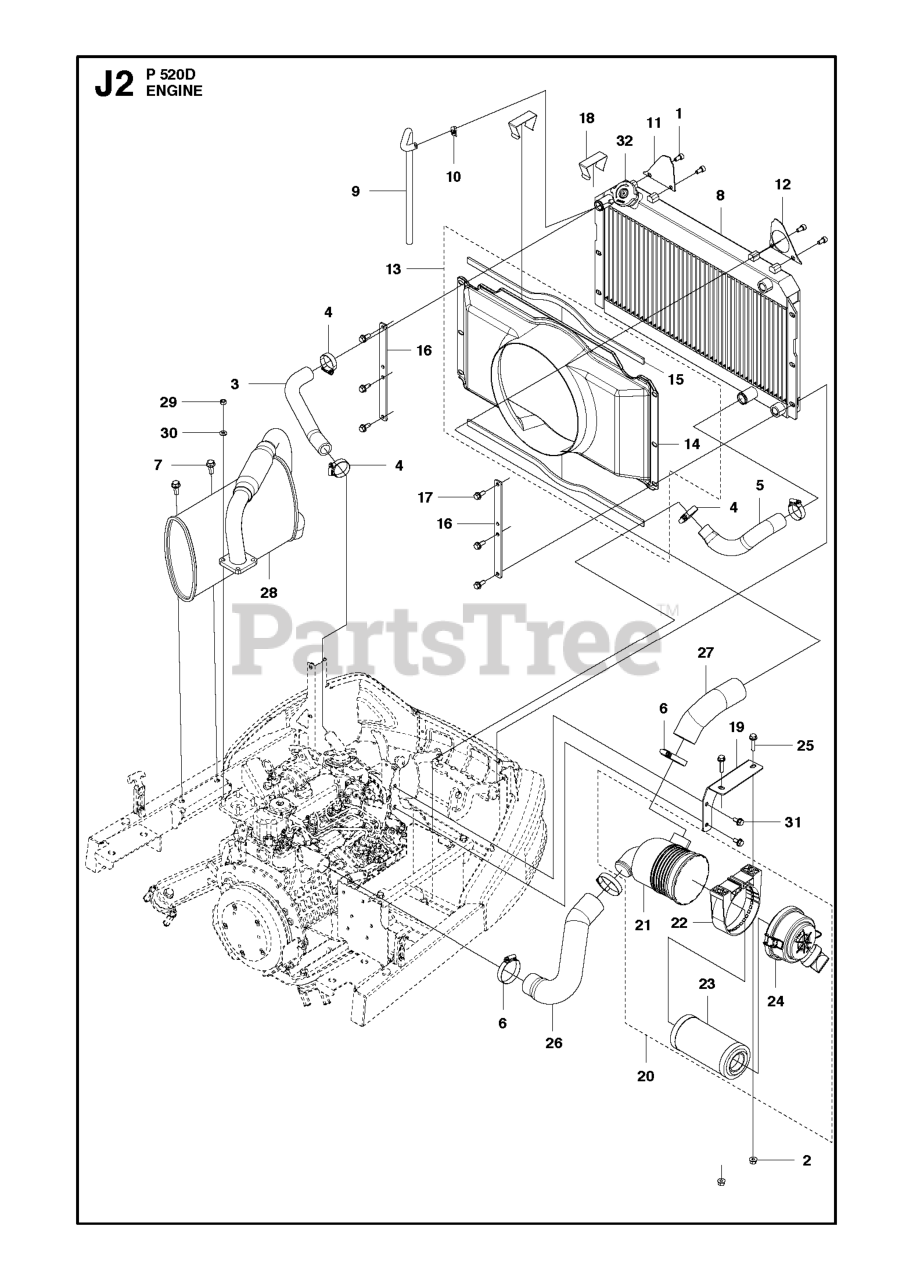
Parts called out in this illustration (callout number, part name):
2	NUT FLANGE
10	RP HOSE CLAMP FUEL HOSE
23	AIR FILTER
24	AIR FILTER END COVER
25	SCREW EHHFM
29	NUT
30	WASHER BRB 8.4X17
